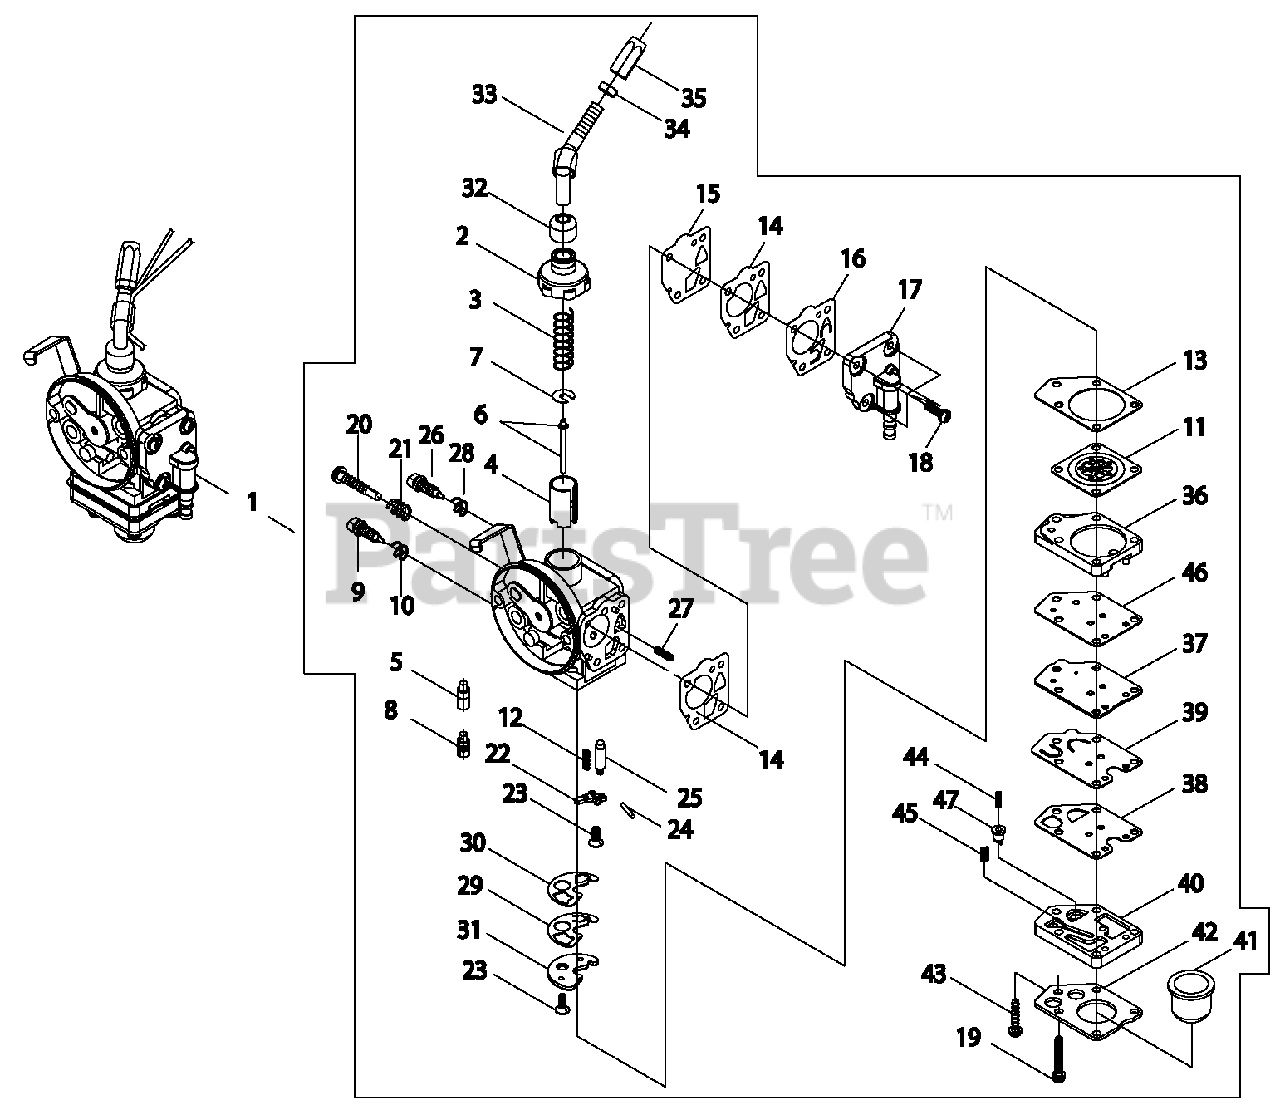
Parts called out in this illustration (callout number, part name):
1	CARBURETOR DPV11W-19A
2	CAP, CARBURETOR
3	SPRING, THROTTLE
4	VALVE, SLIDE
5	JET, MAIN
6	NEEDLE, JET
7	WASHER, SPRING SUPPORT
8	HOLDER, MAIN JET
9	SCREW, MAIN ADJUST
10	SPRING
11	DIAPHRAGM, METERING
12	SPRING
13	GASKET, METERING DIAPHRAGM
14	GASKET, DIAPHRAGM
15	DIAPHRAGM, METERING
16	VALVE, PUMP
17	PUMP BODY
18	SCREW
19	SCREW 3×20
20	SCREW, IDLE ADJUST
21	SPRING
22	LEVER, METERING
23	SCREW M3×8
24	PIN, METERING LEVER
25	VALVE, INLET NEEDLE
26	SCREW, SLOW AIR
27	SPRING
28	SPRING
29	VALVE, CHECK
30	PACKING
31	PLATE
32	CAP, DUST
33	PIPE, CABLE ADJUSTER
34	NUT, LOCK
35	ADJUSTER, CABLE
36	COVER, PUMP
37	GASKET
38	PLATE, PUMP
39	VALVE, CHECK
40	BODY, PURGE
41	BULB, PURGE
42	RETAINER, PURGE BULB
43	SCREW
44	SPRING
45	SPRING
46	GASKET
47	VALVE, CHECK
